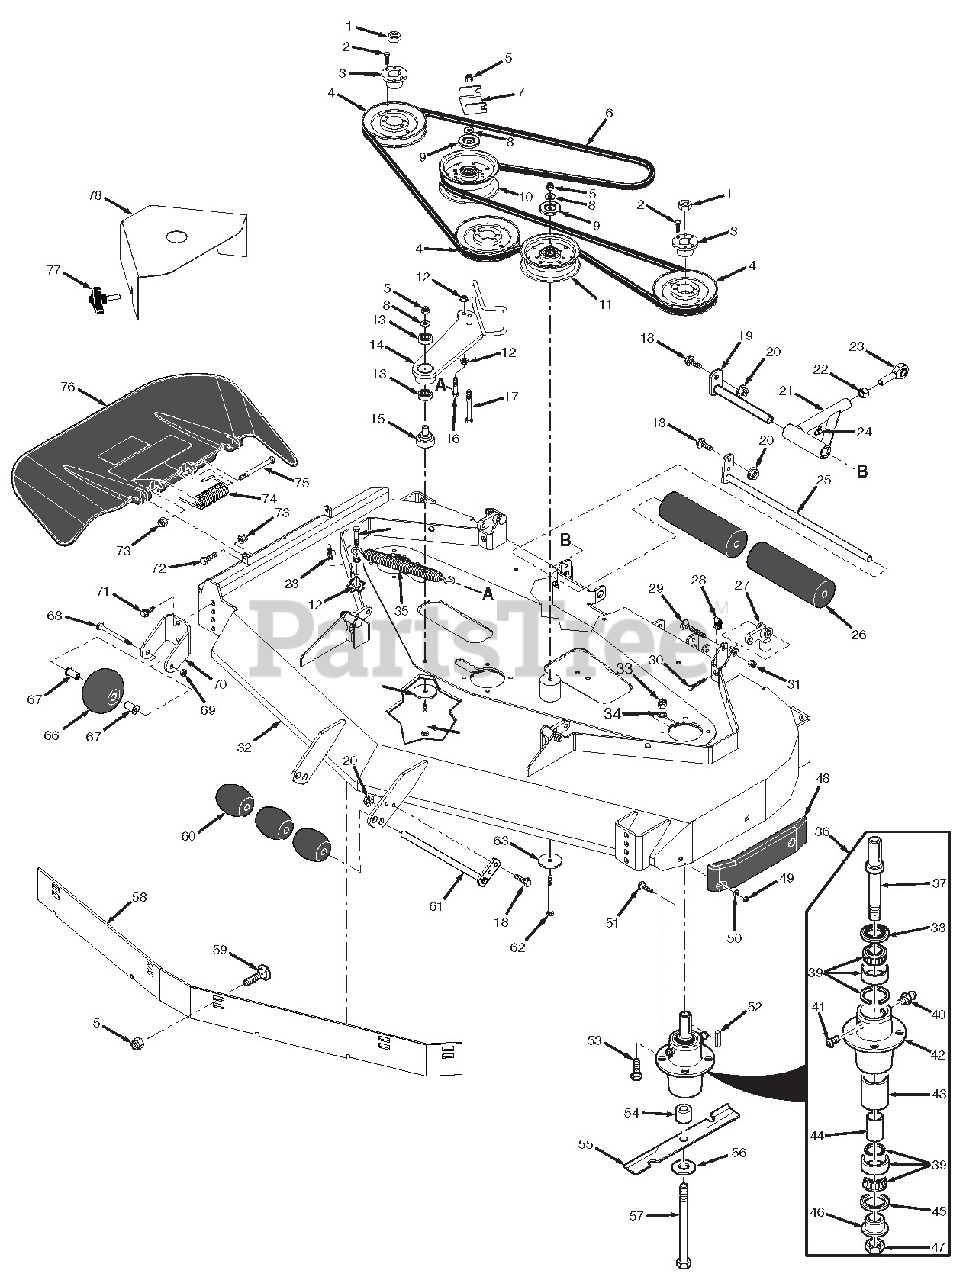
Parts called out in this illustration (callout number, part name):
1	Nut, 5/8-11 UNC
2	Bolt, Hex Head 1/4-20 x 1"
3	Tapered Hub
4	Pulley, 6.32 O.D. (61V)
5	Nut, 3/8-16 Elastic Stop
6	Belt, Cutter Deck (61V)
7	Bracket, Belt Guide
8	Flatwasher, 3/8-.391 x .938 x .105 HD
9	Dust Shield
10	Pulley, 5" Idler
11	Pulley, 5" Idler
12	Nut, Serrated Flange 3/8-16
13	Bearing
14	Idler Arm Assembly
15	Pivot, Idler
16	Bolt, Hex Head 3/8-16 x 1-1/2"
17	Bolt, Hex Head 3/8-16 x 3-1/4"
18	Bolt, Hex Head 5/16-18 x 1"
19	Shaft Weldment, Push Arm Mount
20	Nut, Serrated Flange 5/16-18
21	Pusharm Assembly, LH
21	Pusharm Assembly, RH
22	Nut, 5/8-18 UNF
23	Rod End, Male 5/8"
24	Grease Fitting
25	Shaft Weldment
26	Guide Roller
27	Lever, Deck Level
28	U-Nut, 3/8-16
29	Bolt, Carriage 7/16-14
30	Bolt, Hex Head 3/8-16 x 2" Special
31	Nut, Elastic Stop 7/16-14
32	Cutter Deck w/Decals
33	Nut, Elastic Stop 5/16-18
34	Lockwasher, 5/16" Spring
35	Spring, Cutter Deck
36	Spindle Assembly
37	Shaft, Spindle
38	Seal, Upper
39	Bearing Assembly
40	Grease Fitting
41	Valve Grease Relief
42	Housing, Spindle
43	Spacer, Outside
44	Spacer, Inside
45	Seal, Lower
46	Bushing, Lower
47	Nut, Special 1-1/16" - 18
48	Pad, Deck Wear
49	Nut, Center Lock 5/16-18
50	Flatwasher, 5/16-.344 x .688 x .065
51	Bolt, Carriage 5/16-18 x 3/4"
52	Key, 1/4 x 1/4 x 1"
53	Bolt, Hex Head 5/16-18 x 1-3/4"
54	Spacer, Spindle Bottom
55	Cutter Blade, 21"
56	Flatwasher, 5/8-.688 x 1.75 x .134 HD
57	Bolt, Hex Head 5/8-11 x 9-1/2"
58	Baffle, Flange 61V
59	Bolt, Carriage 3/8-16 x 1"
60	Wheel, Anti-Scalp
61	Shaft Weldment
62	Bolt, Hex Head 3/8-16 x 5"
63	Flatwasher, 3/8-.406 x 2.25 x .1875
64	Bolt, Hex Head 3/8-16 x 3-1/4"
65	Bolt, Hex Head 3/8-16 x 1-1/2"
66	Wheel, Anti-Scalp
67	Bushing, Bronze
68	Bolt, Carriage 3/8-16 x 4"
69	Nut, Center Lock 3/8-16
70	Bracket, Anti-Scalp Wheel
71	Bolt, Hex Head 3/8-16 x 1" Serrated Flange
72	Bolt, Hex Head 5/16-18 x 1-3/4"
73	Nut, 5/16-18 Elastic Stop
74	Spring, Discharge Chute
75	Bolt, Hex Head 5/16-18 x 4-3/4"
76	Discharge Chute Assembly
77	Knob w/Stud
78	Belt Cover, SVR-61V
